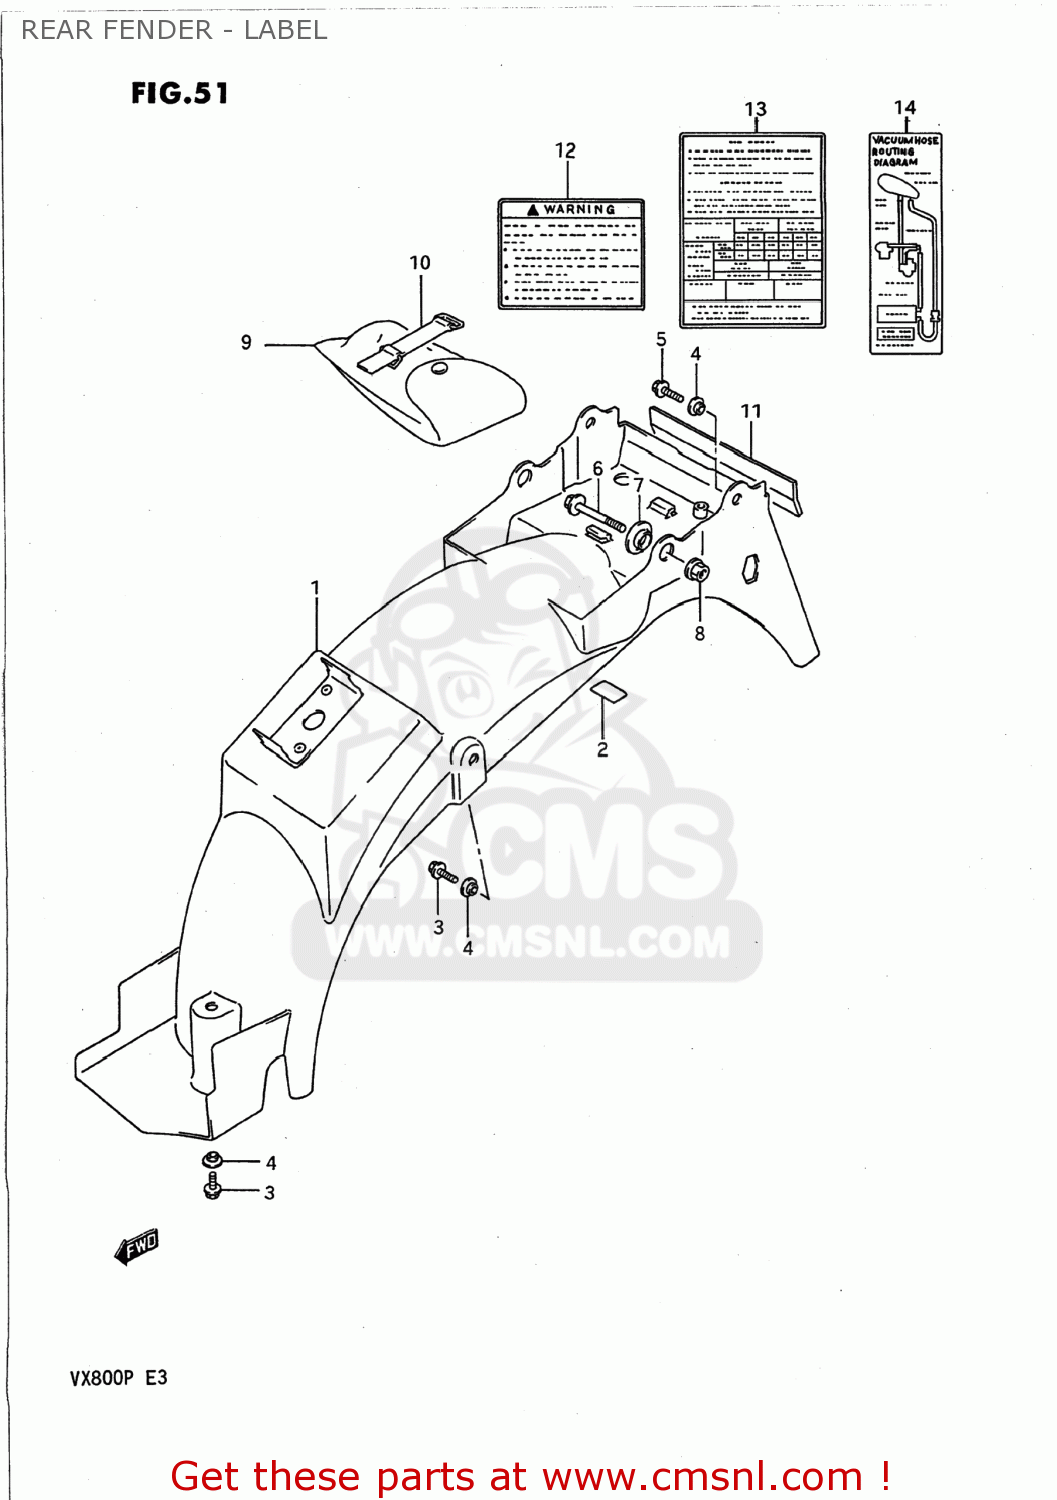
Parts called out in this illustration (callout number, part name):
1	FENDER,REAR
2	TAPE,RR FENDER
3	BOLT
4	WASHER
5	BOLT
6	BOLT
7	WASHER
8	NUT
9	TOOL ASSY
10	BAND
11	CUSHION,RR FENDER
12	LABEL
13	LABEL (TIRE AIR PRESSURE)
14	LABEL (VACUUM HOSE ROUTING)
